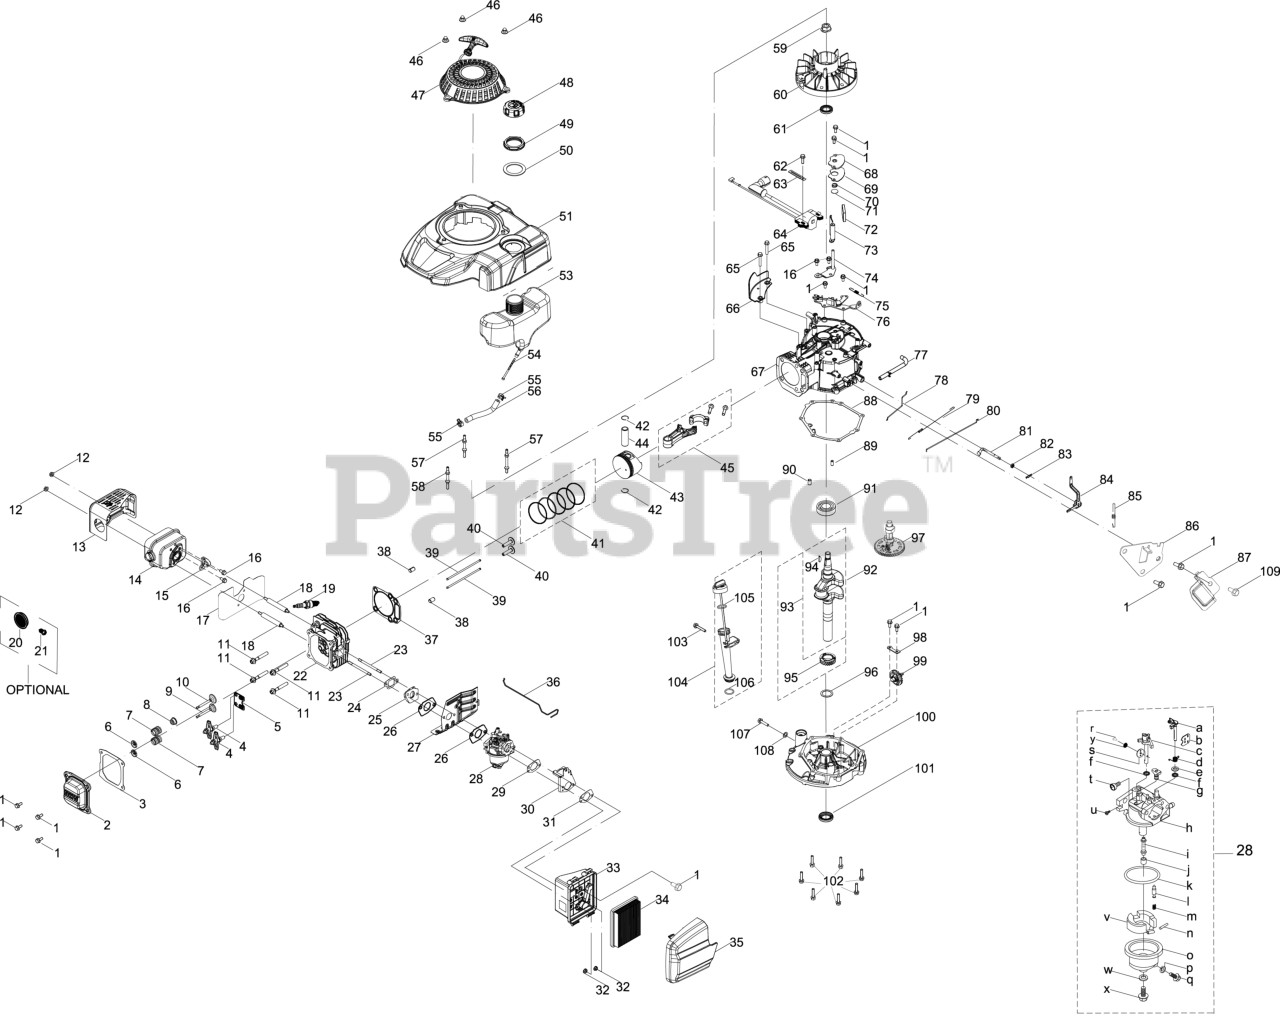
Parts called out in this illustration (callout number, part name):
1	BOLT M6-1 x 14 GR8.8
2	VALVE COVER
3	VALVE COVER GASKET
5	PUSH ROD GUIDE
6	INTAKE VALVE SPRING RETAINER
7	VALVE SPRING
8	INTAKE VALVE SEAL
9	EXHAUST VALVE
10	INTAKE VALVE
11	SCREW M8 x 54 GR10
13	MUFFLER SHIELD
14	MUFFLER ASSEMBLY
15	CHOKE TEMP CONTROL THERMOSTAT
16	BOLT M6-1 x 12 GR8.8
17	MUFFLER GASKET
18	STUD M6-1 x 95
19	SPARK PLUG (F5RTC/RN11YC4/BPR5ES)
20	SPARK ARRESTOR
21	SCREW M3.5 x 9.5
22	CYLINDER HEAD
23	STUD M6 x 90
24	MUFFLER GASKET
25	CARBURETOR INSULATOR
26	CARBURETOR GASKET
27	HEAT SHIELD
28	CARBURETOR ASSEMBLY HY-5X70A
29	AIR FILTER BRACKET GASKET
30	AIR FILTER BRACKET
31	AIR FILTER BASE GASKET
33	AIR FILTER HOUSING BASE
34	AIR FILTER
35	AIR FILTER COVER
36	CHOKE LINKAGE
37	CYLINDER HEAD GASKET
38	PIN (10MMx16MM)
41	PISTON RING 4PC SET
42	PISTON PIN SNAP RING
43	PISTON ASSEMBLY
45	CONNECTING ROD ASSEMBLY
46	ACORN NUT M6-1
47	RECOIL STARTER ASSEMBLY
48	FUEL CAP ASSEMBLY
49	FUEL TANK NUT
50	FUEL TANK GROMMET
51	ENGINE SHROUD
54	FUEL FILTER
55	CARBURETOR HOSE CLAMP
57	STARTER/SHROUD REAR STUD
58	STARTER/SHROUD FRONT STUD
59	FLYWHEEL NUT M14-1.5
61	UPPER CRANKSHAFT SEAL
62	BOLT M6-1 x 20 GR8.8
63	FLEXIBLE CLAMP
64	IGNITION COIL ASSEMBLY
65	BOLT M6-1 x 25 GR8.8
66	ENGINE BRAKE COVER PLATE
68	BREATHER COVER PLATE
69	BREATHER GASKET
70	BREATHER VALVE SPRING
71	BREATHER VALVE
72	BREATHER SCREEN
74	AIR VANE BRACKET
75	ENGINE BRAKE SPRING
76	ENGINE BRAKE ASSEMBLY
77	BREATHER HOSE ASSEMBLY
78	CHOKE LINKAGE
79	THROTTLE SPRING
80	THROTTLE LINKAGE
81	GOVERNOR ARM SHAFT
84	GOVERNOR ARM ASSEMBLY
85	GOVERNOR SPRING
86	COMPONENT BRACKET
87	GOVERNOR SHIELD
88	CRANKCASE COVER GASKET
89	DOWEL PIN 7 X 14
90	DOWEL PIN 9 X 14
92	CRANKSHAFT
93	CRANKSHAFT
94	WOODRUFF KEY
95	DRIVE TIMING GEAR
96	THRUST WASHER
98	GOVERNOR GEAR MOUNTING PLATE
99	GEAR GOVERNOR
100	CRANKCASE COVER
101	LOWER CRANKSHAFT OIL SEAL
102	BOLT-M6-1 x 28 GR8.8
103	BOLT M6-1 x 35 GR8.8
104	OIL DIPSTICK
107	OIL DRAIN PLUG
108	FLAT WASHER
109	BOLT M6-1 x 10 GR8.8
